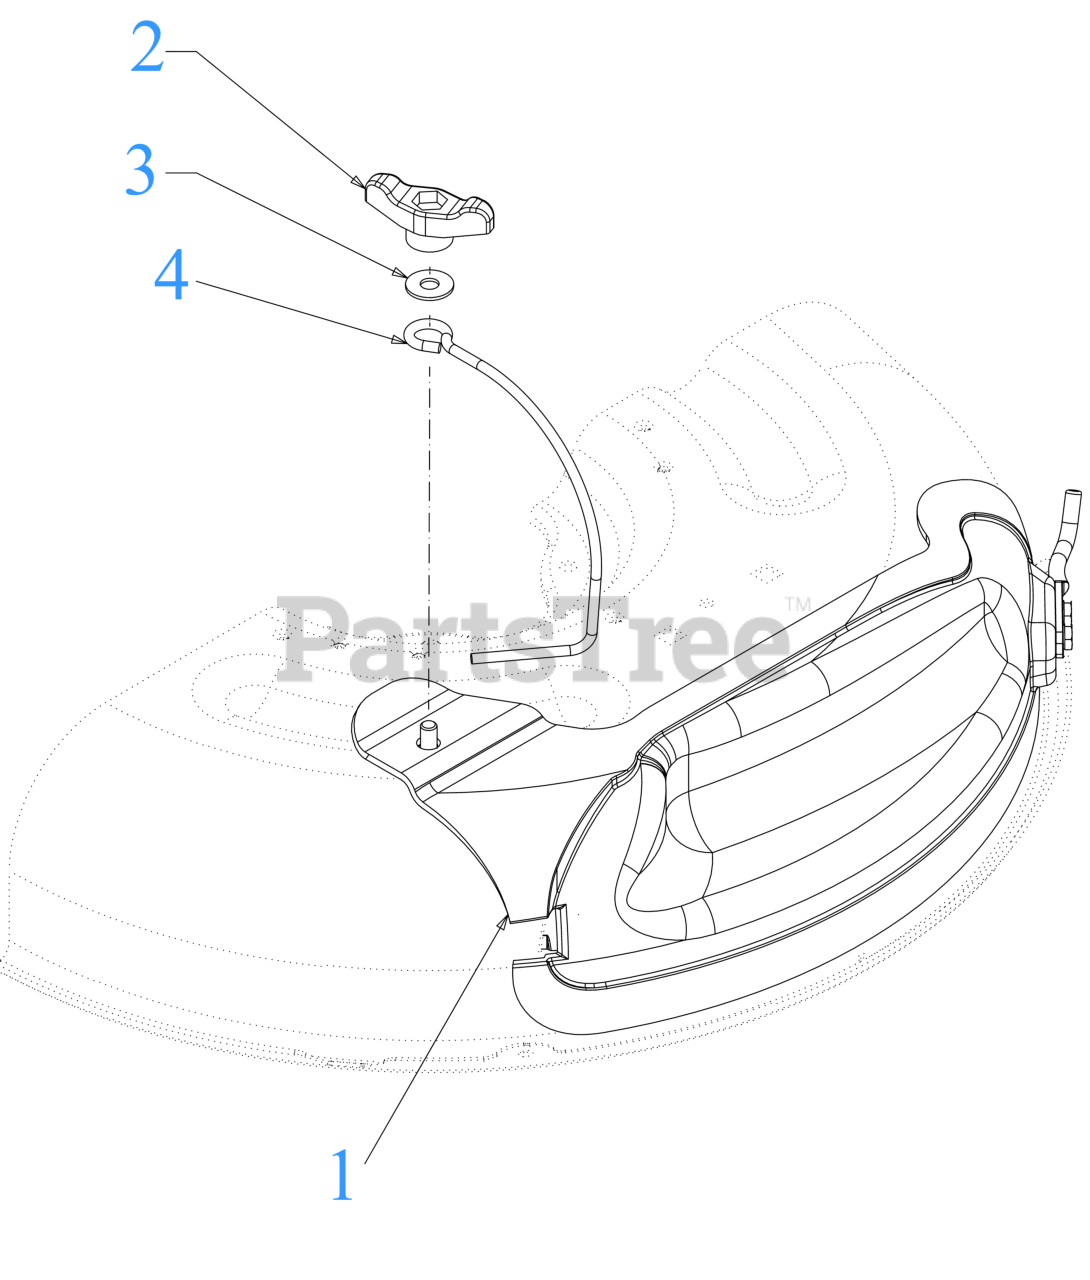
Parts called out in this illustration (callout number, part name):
1	MULCH PLUG ASSEMBLY
1	MULCH PLUG MOUTING ROD
1	FLANGE LOCK NUT
1	SCREW 1/4-20X.75 GR5
1	SPRING WASHER BELL
2	WING KNOB 5/16-18
3	FLAT WASHER
4	MULCH PLUG SUPPORT ROD
